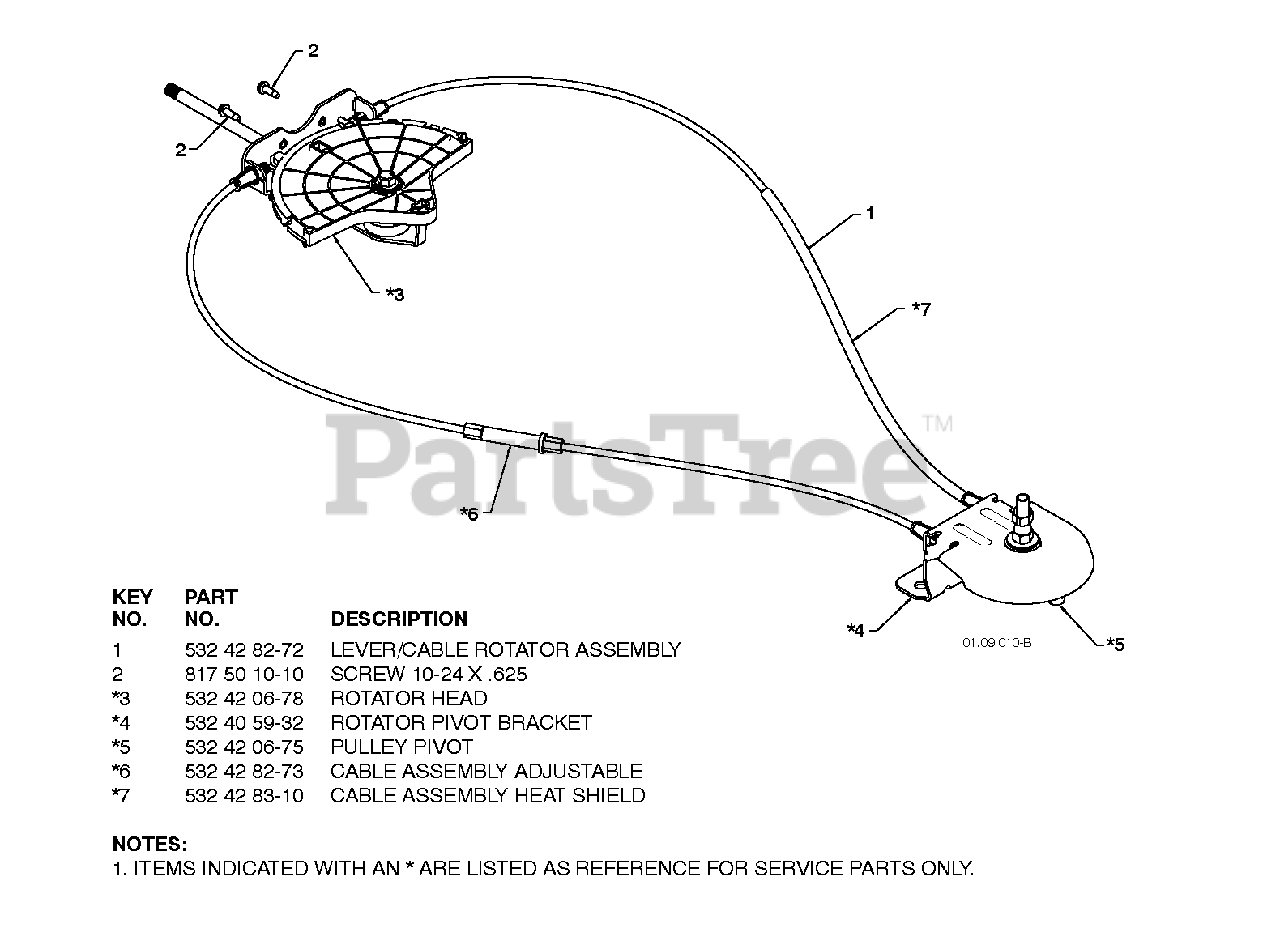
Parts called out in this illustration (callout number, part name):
1	LEVER/CABLE.ASM.ROTATOR
2	SCREW #10-24 X 5/8
3	CHUTE.ROT.HEAD.SERVICE
4	SNOW.PIVOT.BRKT.BLK.SERVICE
5	SNOW.PIVOT.PULLY
6	SNOW.CBL.ASM.ADJ.SERVICE(74)
7	SNOW.CBL.ASM.SERVICE(428272)
